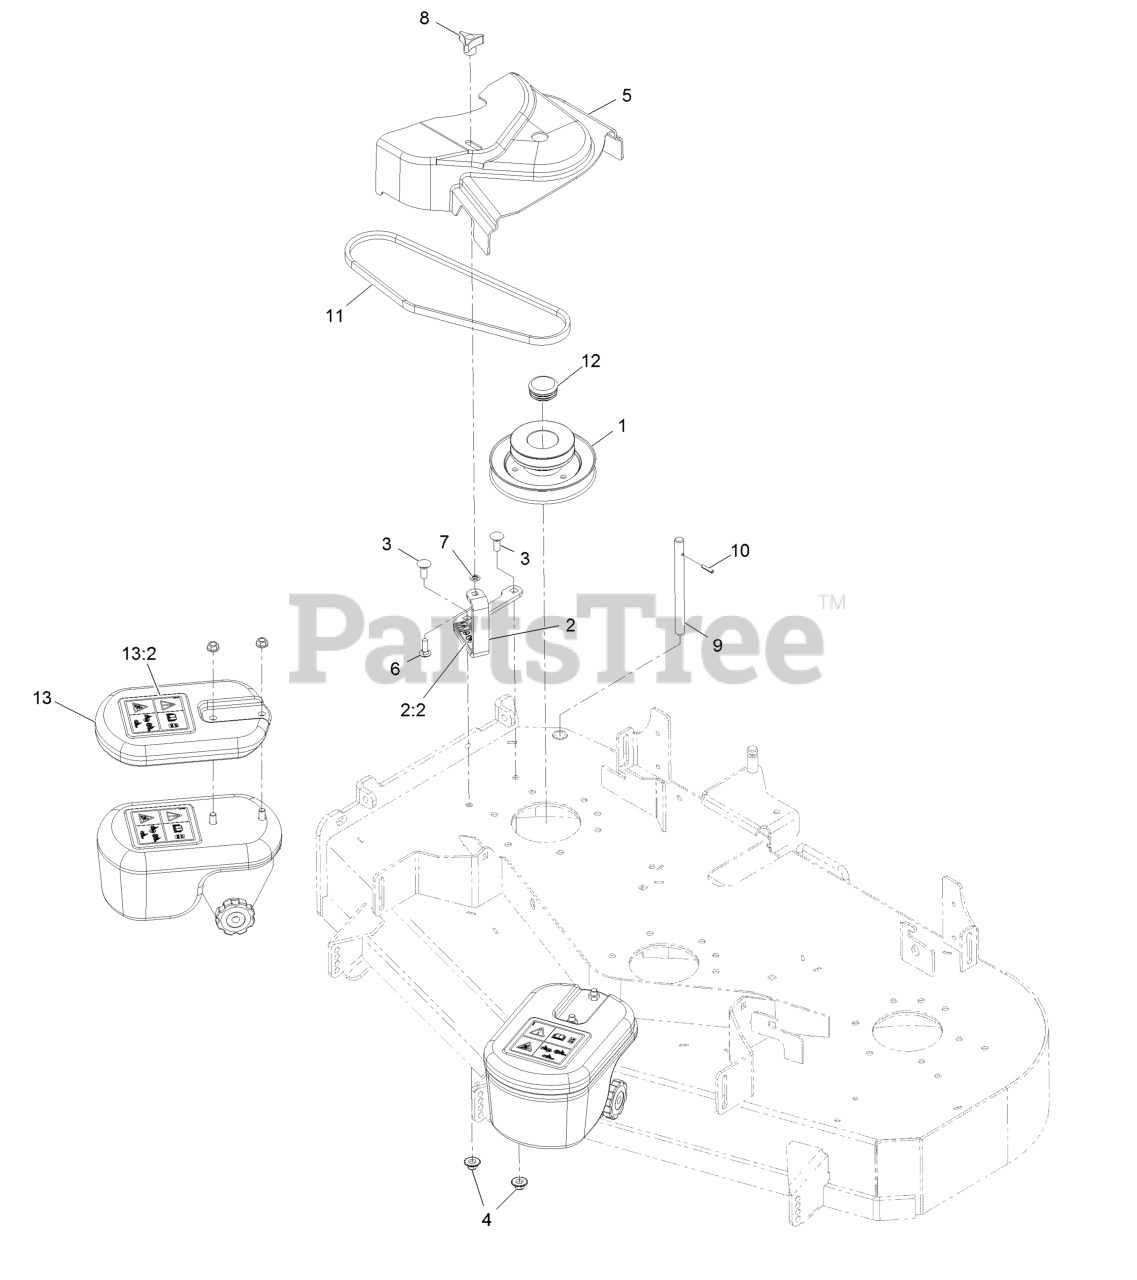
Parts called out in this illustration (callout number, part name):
1	JACKSHAFT-UV DRIVE, 484 S
2	ASM-CVR BRKT W/DECAL
2:2	DECAL-DANGER
3	BOLT-CARR
4	Nut-Nyloc 3/8-16 Flg
5	COVER-BELT, UV 48
6	BOLT-CARR
7	RING-RETAINING, BOLT
8	KNOB-3 PRONG
9	SHAFT-CATCHER, GRASS
10	PIN-ROLL
11	BELT-UV E 48
12	PLUG-ROUND PLASTIC
13:2	DECAL-WARNING, TRACTION
